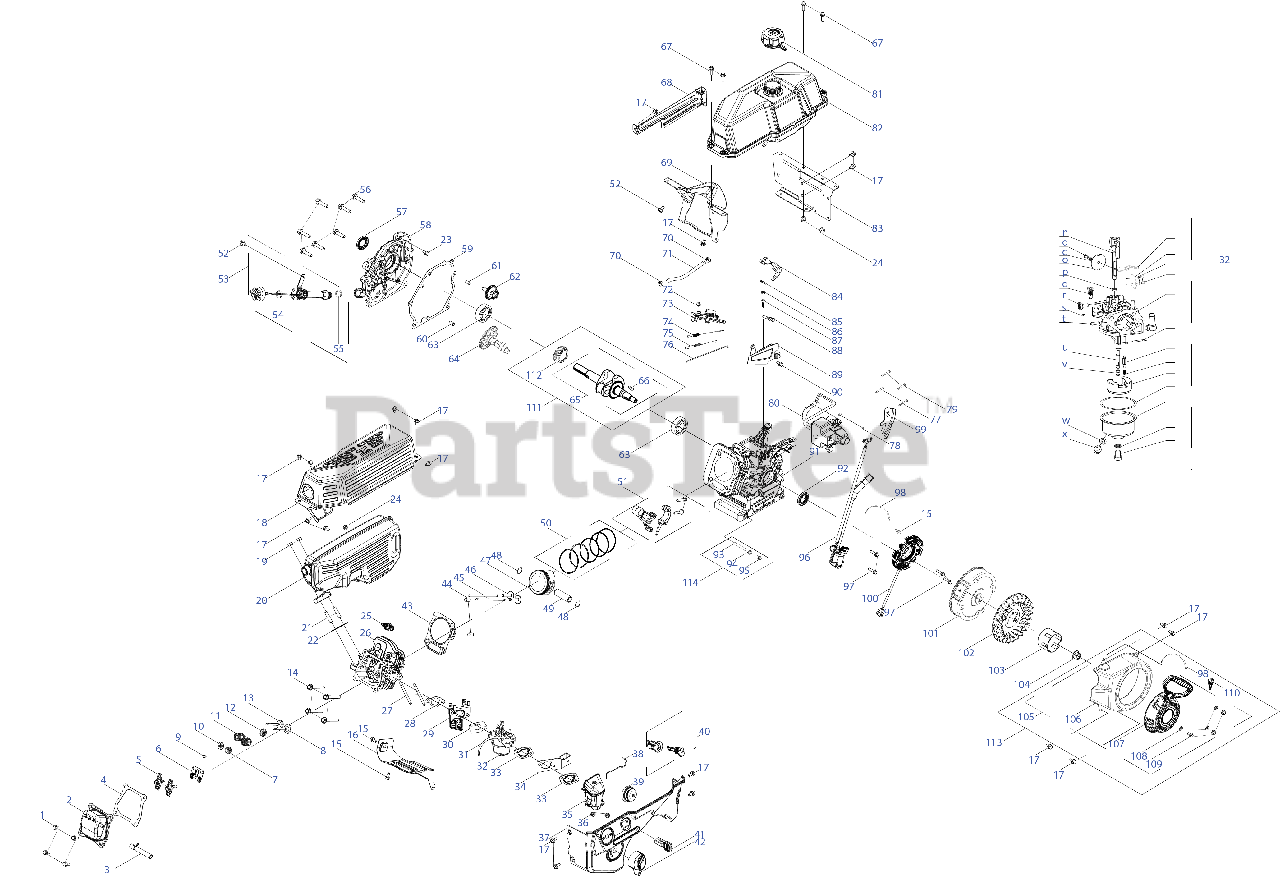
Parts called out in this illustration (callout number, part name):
1	BOLT M6 x 16
2	VALVE COVER
3	BREATHER HOSE
4	VALVE COVER GASKET
5	ROCKER ARM ASSEMBLY
6	ROCKER ARM BASE
7	INTAKE VALVE SPRING RETAINER
8	INTAKE VALVE
9	EXHAUST VALVE ADJUSTER
10	EXHAUST VALVE SPRING RETAINER
11	VALVE SPRING
12	INTAKE VALVE SEAL
13	EXHAUST VALVE
14	BOLT M8-1.25 x 55 GR10.9
15	BOLT M6-1 x 12 GR8.8
16	AIR SHIELD
17	BOLT-M6 x 12
18	MUFFLER GUARD
21	STUD M8-1.25 x 36
22	MUFFLER GASKET
23	SCREW M6-1 x 20 CL5.8
25	SPARK PLUG
26	CYLINDER HEAD
27	STUD M6 x 92
28	CARBURETOR INSULATOR GASKET
29	CARBURETOR INSULATOR
30	CARBURETOR GASKET
31	PRIMER HOSE
32	CARBURETOR ASSEMBLY
33	CARBURETOR GASKET PLATE
34	CHOKE CONTROL
35	HEATER BOX
37	CONTROL PANEL
40	ENGINE KEY SWITCH ASSEMBLY
41	THROTTLE CONTROL KNOB
42	CHOKE LEVER
43	CYLINDER HEAD GASKET
45	PUSH ROD
48	PISTON PIN SNAP RING
49	PISTON PIN
50	PISTON RING SET
51	CONNECTING ROD ASSEMBLY
52	BOLT-M6 x 16
53	DIPSTICK ASSEMBLY
54	DIPSTICK O-RING
55	O-RING 15.8 x 2.5
56	BOLT M8-1.25 x 32 GR5.8
57	OIL SEAL
58	CRANKCASE COVER
59	CRANKCASE COVER GASKET
60	DOWEL PIN
61	DOWEL PIN
62	GOVERNOR GEAR/SHAFT ASSEMBLY
65	CRANKSHAFT
66	FLYWHEEL KEY
67	BOLT-M6 x 22
68	FUEL TANK INSULATOR
69	FRONT FUEL TANK BRACKET
70	HOSE CLAMP
72	BOLT M6-1 x 12 GR8.8
73	GOVERNOR GEAR BRACKET
74	GOVERNOR SPRING
75	THROTTLE RETURN SPRING
76	GOVERNOR ROD
77	BOLT M6-1 x 32 GR8.8
78	DOWEL PIN
79	BOLT-M4 x 55
80	ELECTRIC STARTER
83	FUEL TANK INSULATOR
84	GOVERNOR LEVER
85	COTTER PIN
86	GOVERNOR SEAL
88	GOVERNOR SHAFT
89	AIR FLOW SHIELD
90	BOLT M6-1 x 10 GR8.8
92	OIL SEAL
93	OIL DRAIN PIPE
94	WASHER
95	OIL DRAIN PLUG
96	IGNITION MODULE
97	BOLT M6-1 x 25 GR8.8
98	CABLE TIE - 3 x 150
99	LOWER SHIELD
100	IGNITION MODULE
102	COOLING FAN
103	STARTER CUP
104	FLYWHEEL NUT
105	RECOIL HOUSING ASSEMBLY
106	BLOWER HOUSING
107	RECOIL STARTER ASSEMBLY
108	RECOIL FLAT WASHER
109	HEX FLANGE BOLT M6-1 x 10 GR8
110	IGNITION KEY
111	CRANKSHAFT
112	TIMING GEAR
113	RECOIL STARTER
114	OIL PIPE ASSEMBLY
